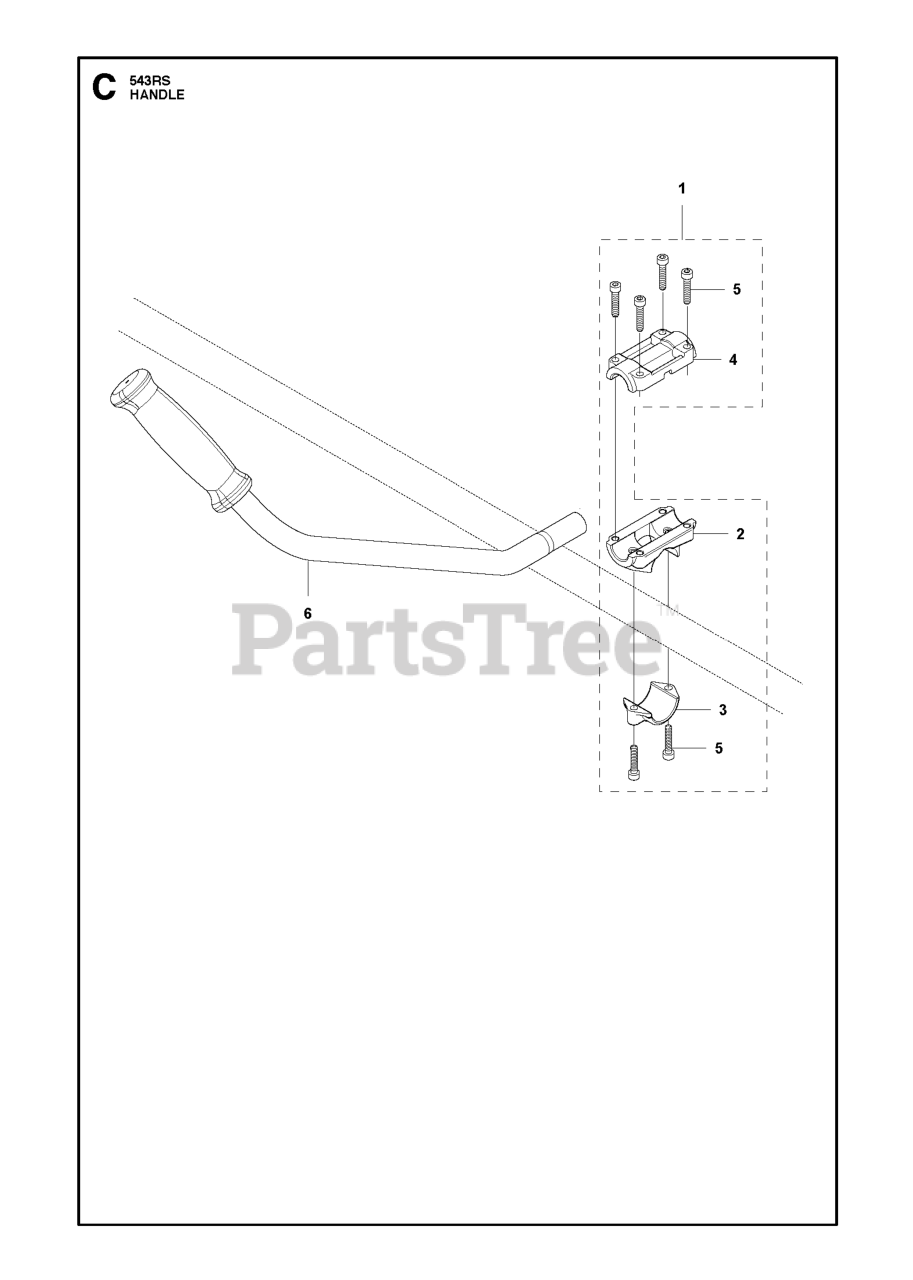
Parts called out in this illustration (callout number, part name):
1	HANDLE BRACKET ASSY 243R
2	BRACKET Z354314112
3	CAP-L Z354314121
